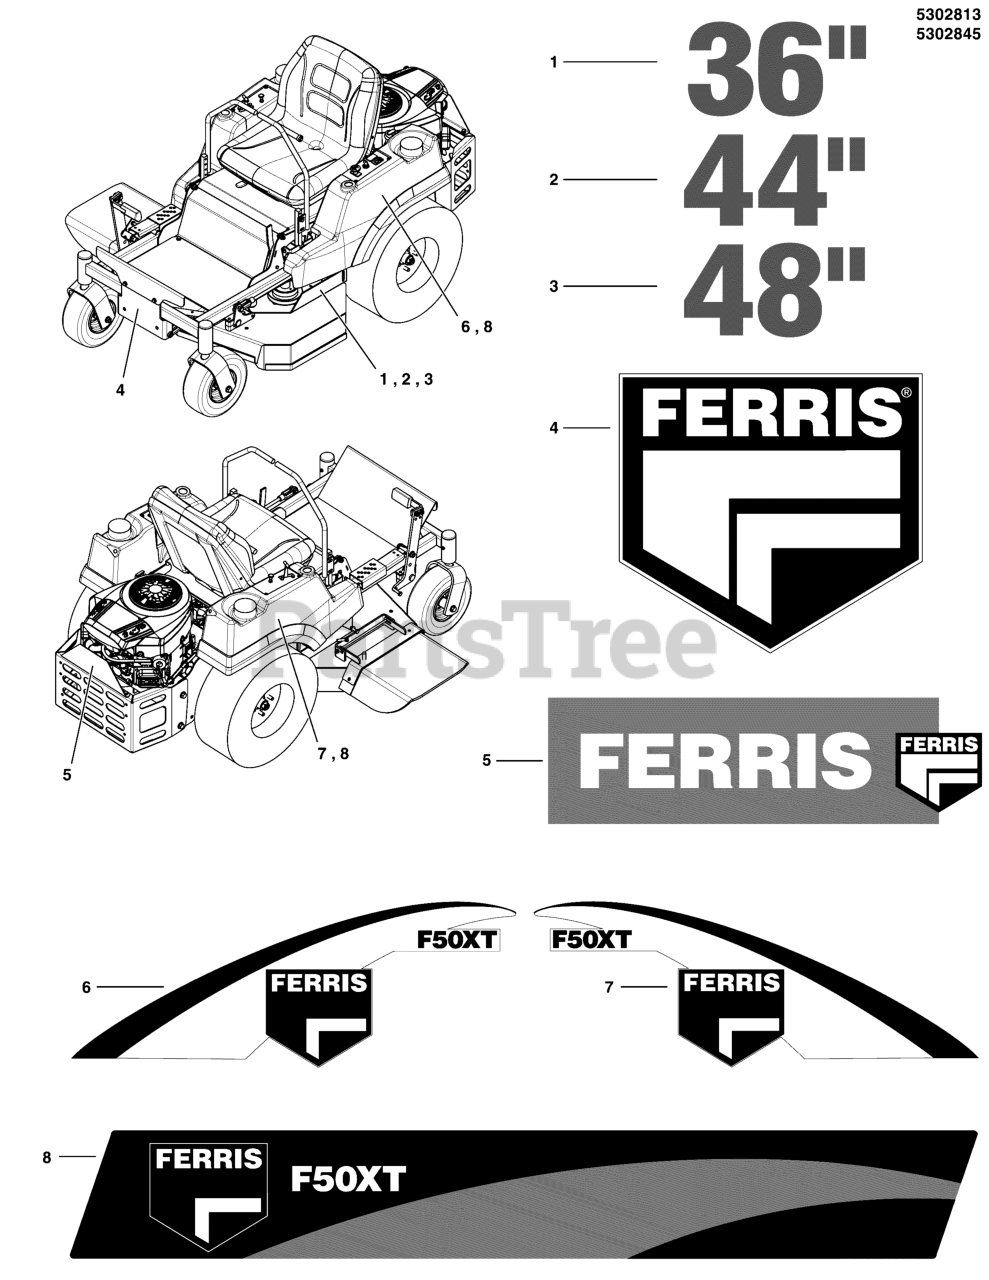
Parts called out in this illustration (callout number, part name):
1	DECAL, 36
2	DECAL, 44
3	DECAL, 48
4	DECAL, FERRIS LOGO, MEDIUM
5	DECAL, FERRIS TEXT & LOGO
6	DECAL, BADGE, LH, F50XT
7	DECAL, BADGE, RH, F50XT
8	DECAL, BADGE, F50XT
